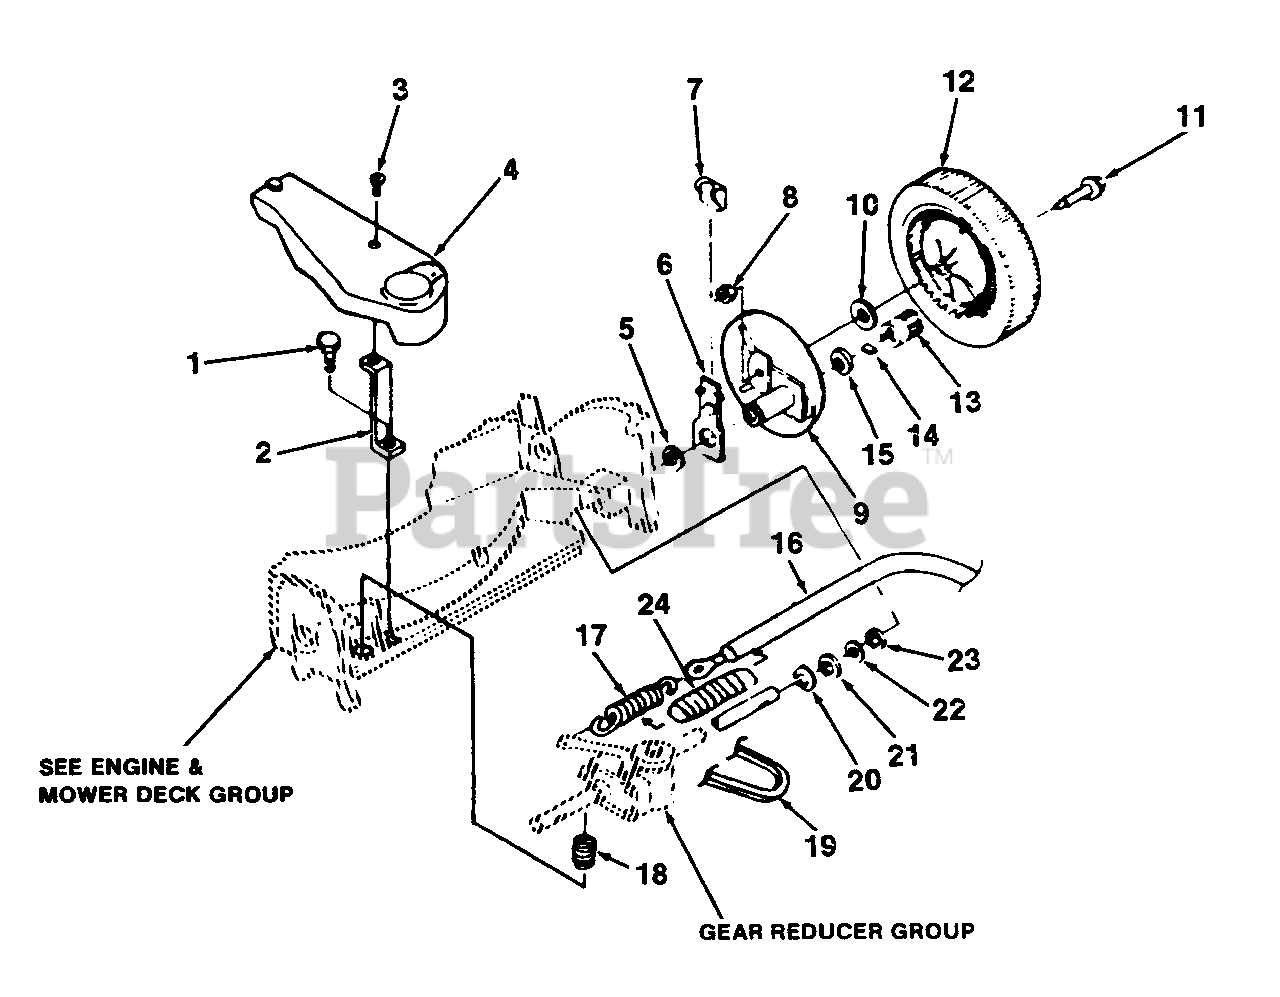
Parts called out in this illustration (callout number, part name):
1	SCREW, Hex Hd., 10-16 x 1/2
3	SCREW, 1/4-20 x 3/4
4	COVER, Drive (Mfg. No. 1691727, 1691729 Only)
4	COVER, Clutch (Mfg. No. 1691728 Only)
6	SPRING, Index
8	NUT, 3/8-16
9	SUPPORT, Drive Wheel
11	BOLT & NUT ASSY. (Incl. Ref. No. 8)
12	WHEEL & TIRE
13	PINION, R.H.
13	PINION, L.H.
14	PAWL, Pinion
16	CABLE, Traction
17	SPRING, Extension
18	SPRING, Compression
19	BELT, Drive
20	RING, Eaton
22	WASHER (Use as Shim)
24	COVER, Spring
